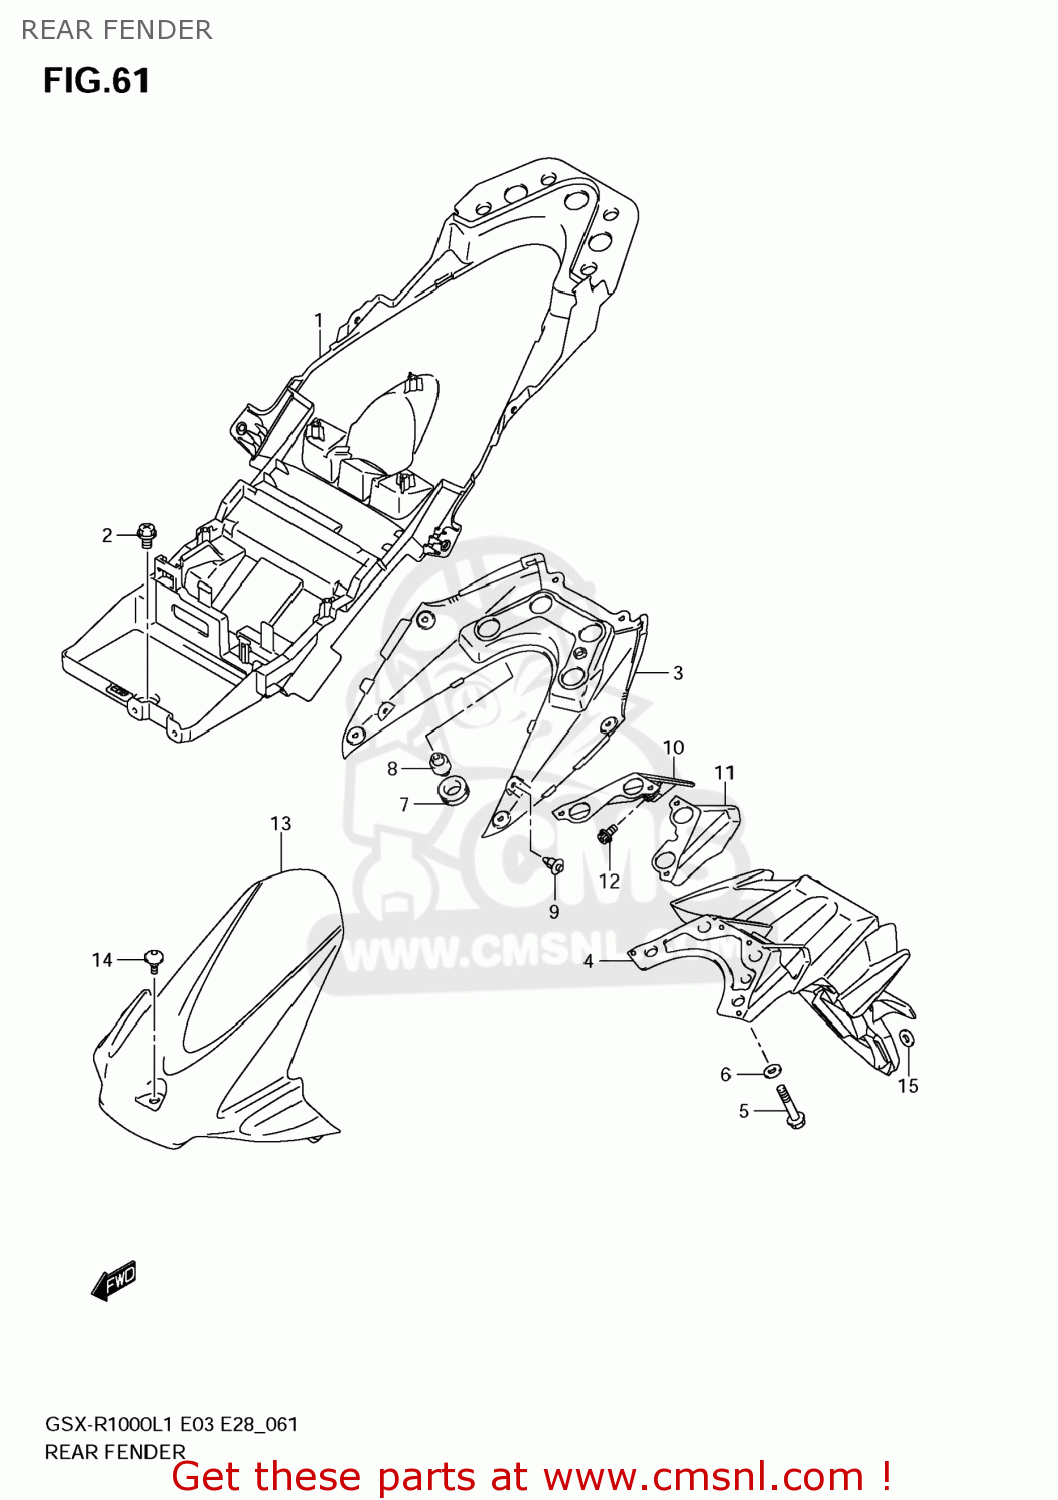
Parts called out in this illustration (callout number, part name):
1	FENDER, REAR FRONT
2	BOLT
3	SPATBORD.ACHTER
4	FENDER,RR RR
5	BOLT(6X30)
6	WASHER(6.5X18X1)
7	CUSHION
8	SPACER,RR FENDER RR
9	CLIP(BLACK)
10	COVER,RR FENDER RR,R
11	COVER,RR FENDER RR,L
12	BOLT
13	FENDER,RR LWR
14	SCREW(6X16)
15	WASHER
